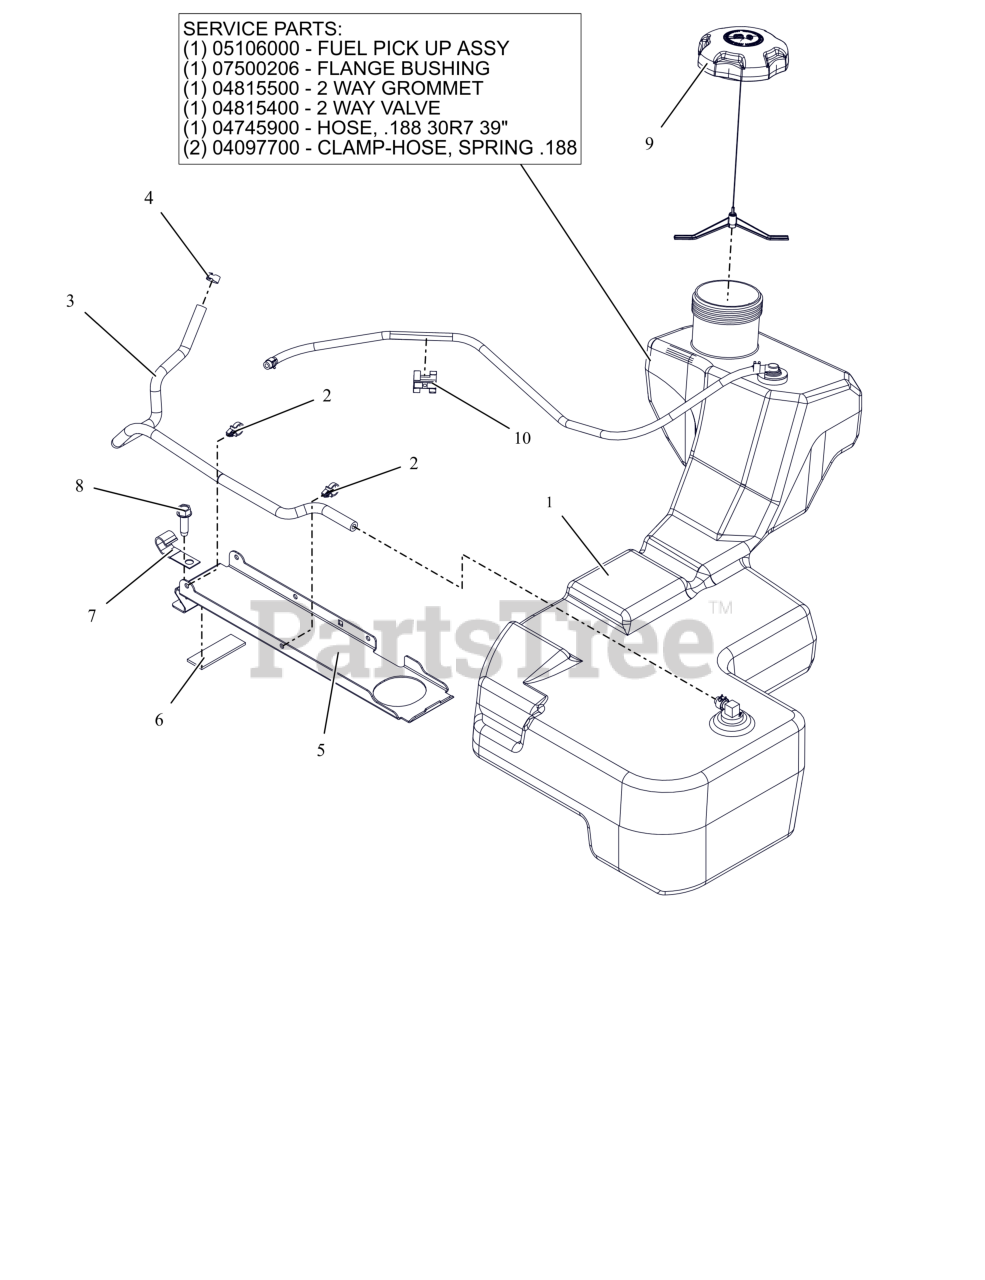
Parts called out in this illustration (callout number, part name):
1	ASM, FUEL TANK-HD
2	ROUTING CLIP (1/2" ID)
3	HOSE, .25 LOW-PERM BULK GAS, SOLD BY THE INCH
4	CLAMP, FUEL LINE
5	BRKT, FUEL TANK HOLD DOWN
6	PAD,RBR 1.0"X3.0" W/ADHESIVE
7	J-CLAMP
8	SCR,TAP .375-16X1.25HWH TR ZCC
9	CAP, FUEL - 3.50 RATCHET INLET VENT
10	CLIP, T, .38-.50
